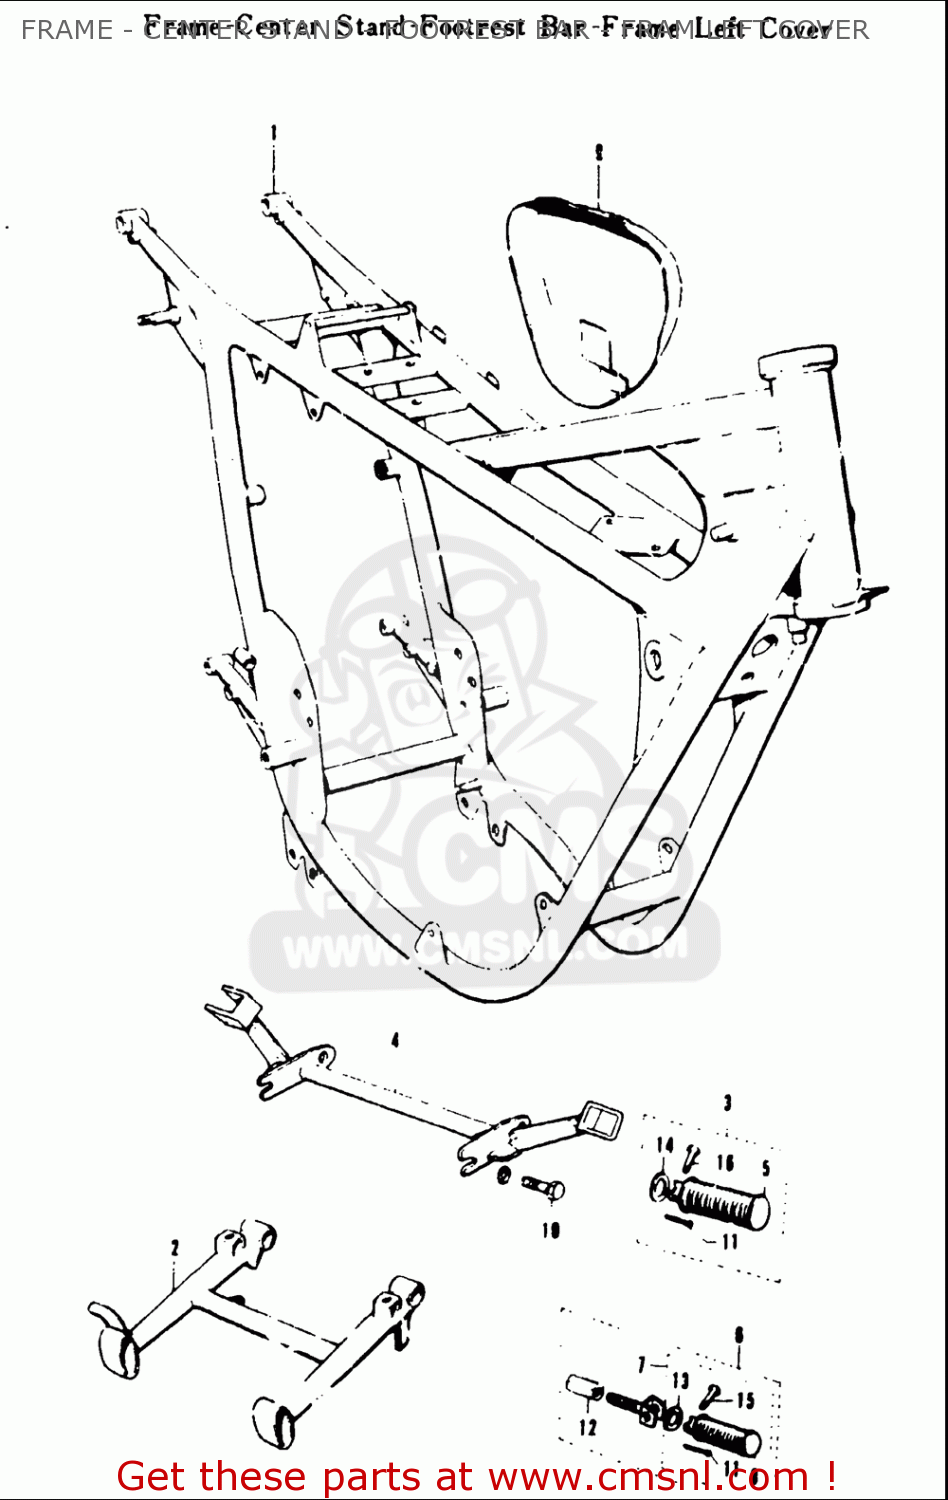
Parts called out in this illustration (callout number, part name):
10	BOLT
12	NUT
13	WASHER(19.5X32X2)
14	WASHER(22.5X38X1)
15	PIN
16	PIN
